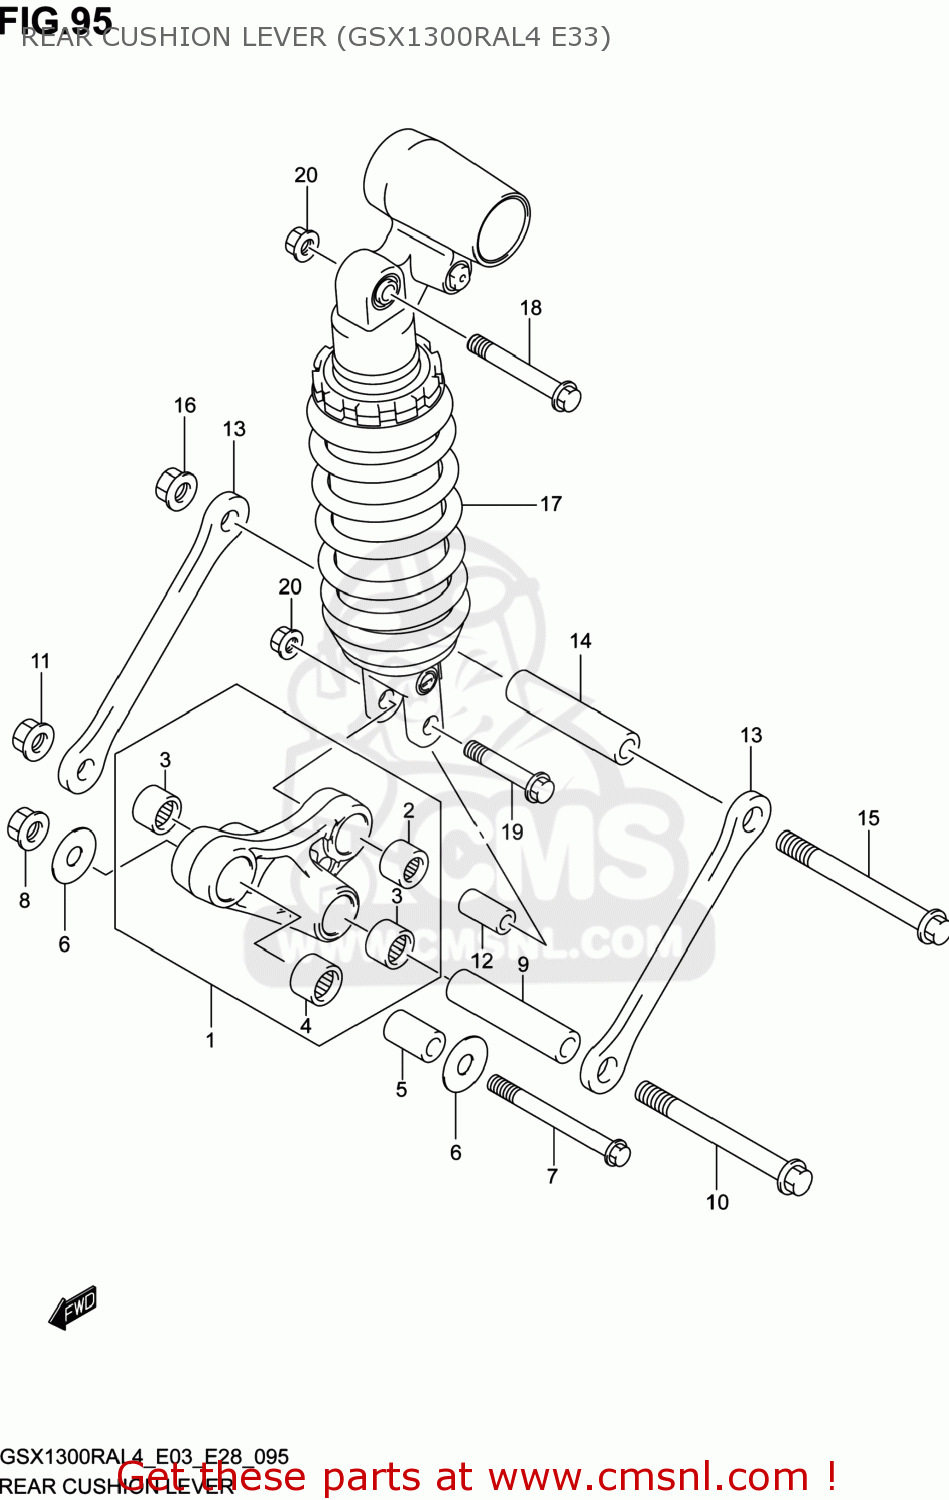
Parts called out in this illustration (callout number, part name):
1	LEVER SET,RR CUSHION
2	BEARING(20X27X30)
3	BEARING(17X24X25)
4	BEARING(17X24X26)
5	SPACER,RR CUSHION LEVER FR
6	WASHER
7	BOLT,RR CUSHION LEVER FR
8	NUT
9	SPACER,RR CUSHION LEVER CTR
10	BOLT,RR CUSHION LEVER CTR
11	NUT
12	SPACER,RR CUSHION LEVER
13	ROD,RR CUSHION
14	SPACER,RR CUSHION LEVER CTR
15	BOLT,RR CUSHION LEVER CTR
16	NUT
17	ABSORBER ASSY,RR SHOCK
18	BOLT(10X70)
19	BOLT(10X55)
20	NUT
